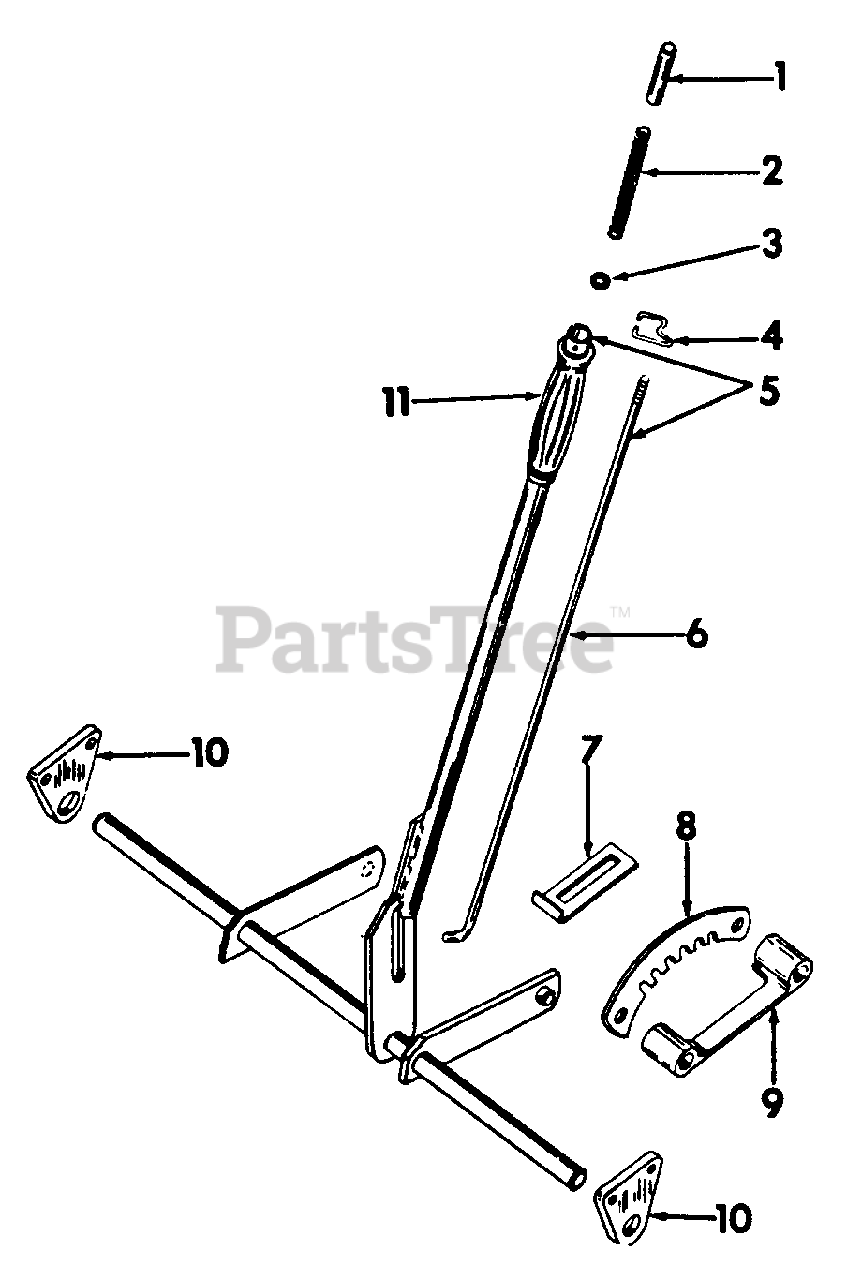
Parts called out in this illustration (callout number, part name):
1	Pin, Handle Release Rod
2	Spring, Release Rod Return
3	Washer, Release Rod Return Spring
4	Lock, Release Rod
5	Handle Assy, Lift
6	Rod, Handle Release
7	Stop, Lift Arm
8	Ratchet, Lift
9	Spacer Assy, Lift Ratchet
10	Bracket, Lift Handle Shaft
11	Grip, Lift Handle
